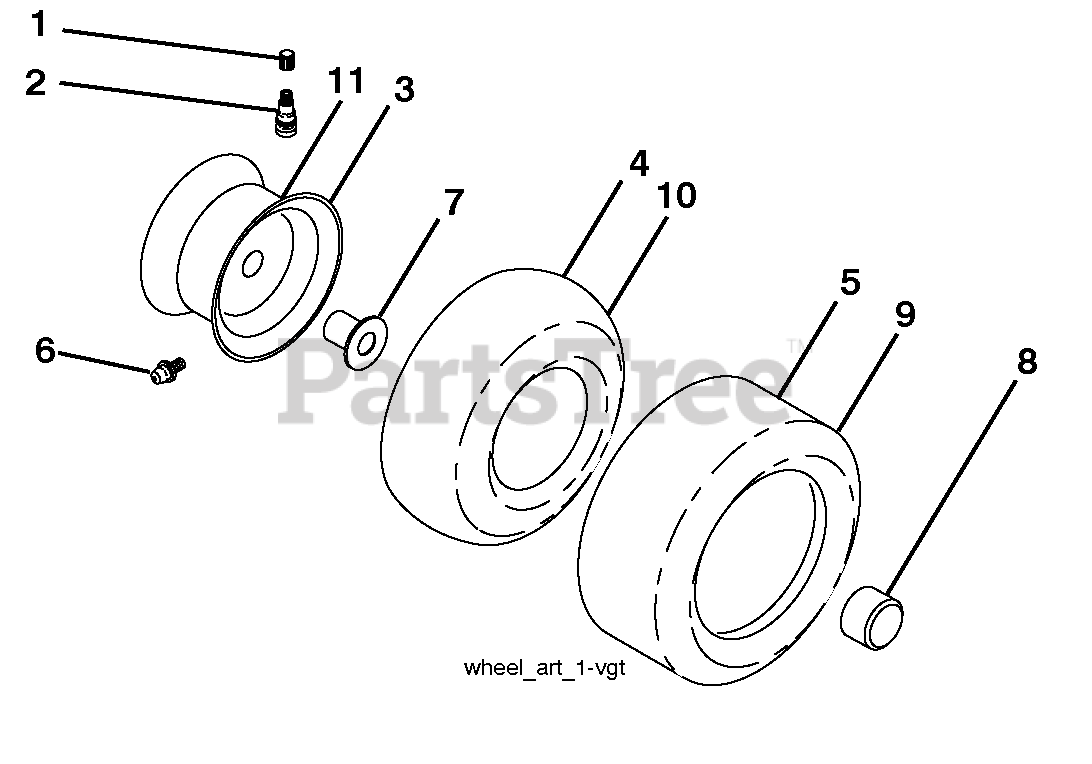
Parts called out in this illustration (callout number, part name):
1	Cap, Valve, Tire
2	Stem, Valve
3	Rim Assembly, Front
4	Tube, Front
5	Tire, Front
6	Fitting, Grease
7	Bearing, Flange
8	Cap, Axle
9	Tire, Rear 18 x 9.5-8 Turf Saver
9	Tire, Rear 18 x 9.5-8 Turf Saver LT
10	Tube, Rear
11	Rim Assembly, Rear
11	Sealant, Tire (10 oz. Tube)
